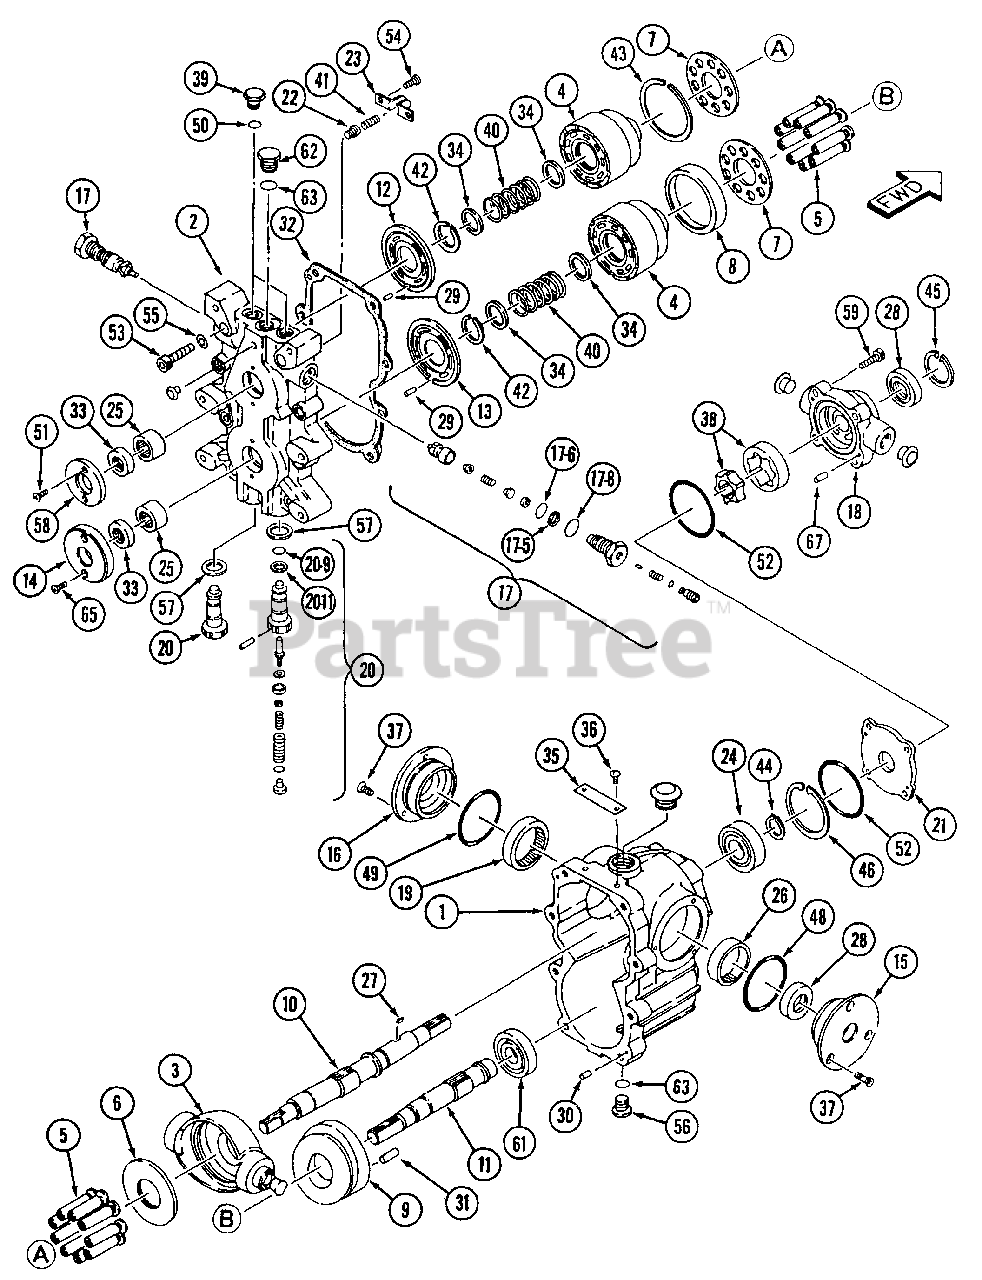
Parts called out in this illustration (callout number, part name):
4	Cylinder Block
5	Piston S/A
6	Plate, Thrust
7	Plate, Retainer
8	Holder, Retainer
9	Swash, Plate
15	Cover A
16	Cover B
17-5	Ring, Back Up
18	Charge Pump
19	Bearing, Needle
20-11	Ring, Back Up
23	Holder, Spring
24	Bearing, Ball
25	Bearing, Needle
26	Bushing
34	Holder, Spring
35	Plate, Name
36	Screw, Drive
38	Trochoid Rotor S/A
40	Spring
42	Ring, Snap
55	Washer, Spring
61	Bearing, Ball
